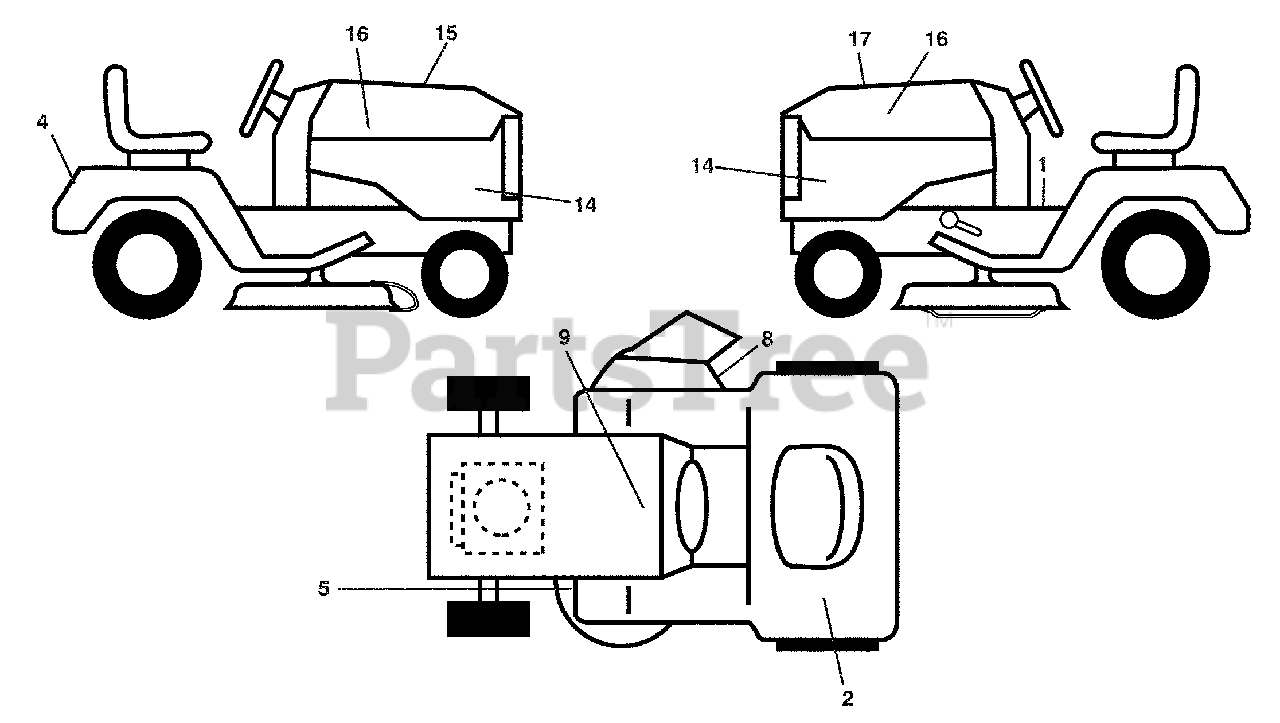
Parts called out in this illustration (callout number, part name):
1	Decal, Warning
2	Decal, Ethanol E85
4	Decal, Hood Cust Resp
5	Decal, Caution
8	Decal, Mower Sch.
9	Decal, Battery Dnge/Poi
14	Decal, Panel Side
15	Decal, Panel Side
16	Decal, Hood Logo
17	Decal, Replacement
18	Decal, Bypass
19	Pad, Footrest, LH
20	Pad, Footrest, RH
